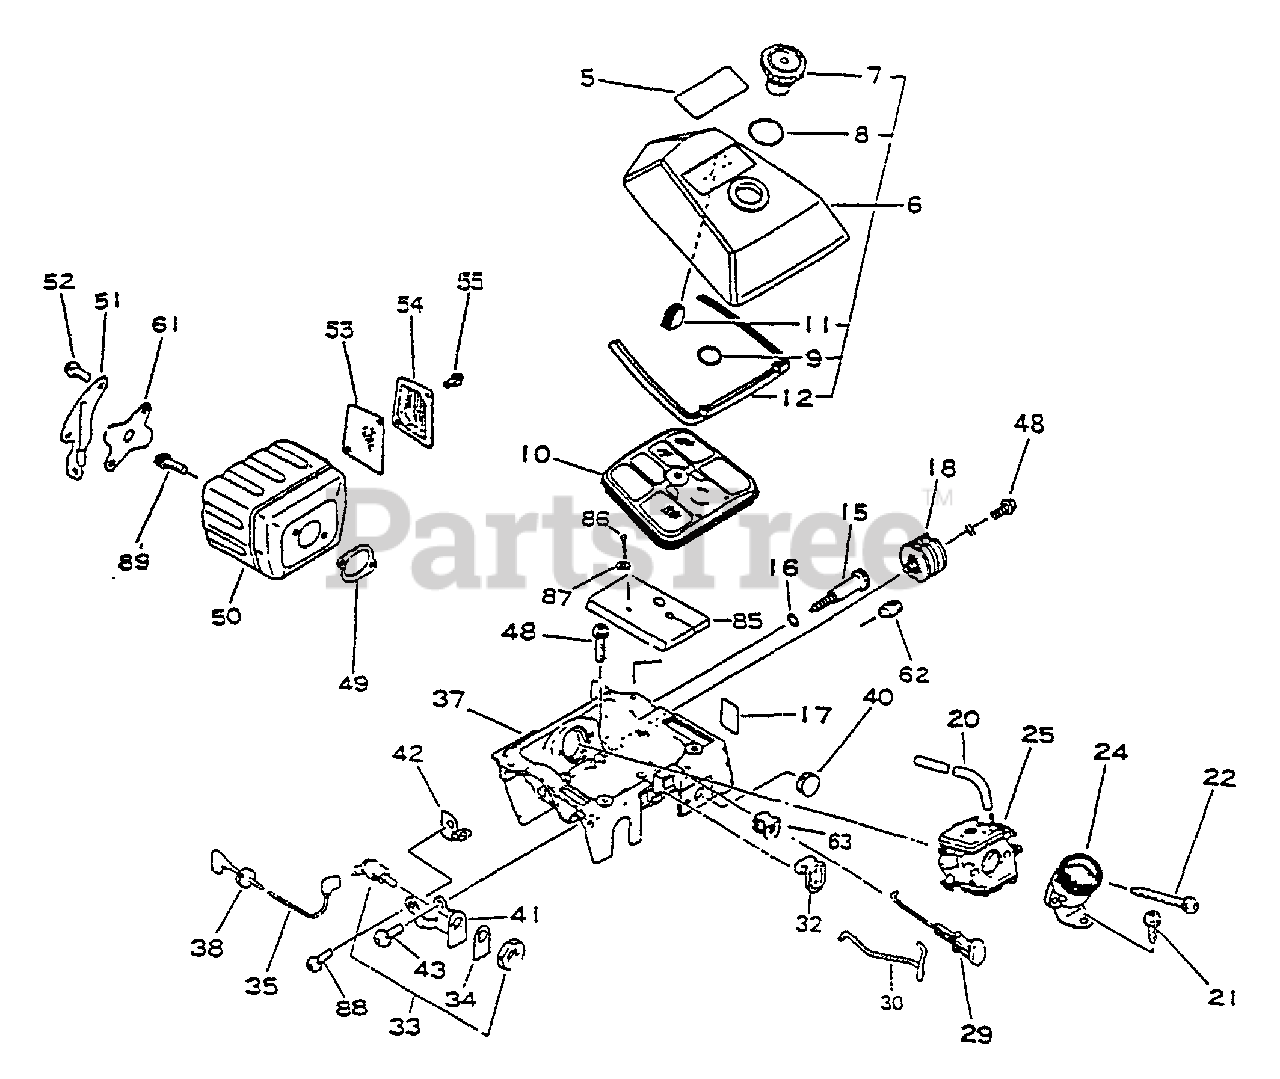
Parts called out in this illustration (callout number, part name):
5	LABEL, CS-5500
6	COVER ASSY, AIR FILTER
7	THUMBSCREW
8	O-RING 22
9	O-RING P-11
10	FILTER ASSY, AIR
12	GASKET, AIR FILTER
15	SCREW, IDLE ADJUST - GRAY
16	O-RING 7 MM
17	LABEL, CAUTION - IDLE
20	PIPE, IMPULSE
21	SCREW 5×14
22	SCREW - 5×35
24	ADAPTER, INTAKE
25	CARBURETOR
29	ROD, CHOKE
30	ROD, THROTTLE
32	ROD, THROTTLE
33	SWITCH, ON-OFF
34	LABEL - SWITCH
35	LEAD - GROUND
37	CASE, CARBURETOR
41	BRACKET, SWITCH
42	PLATE, GROUND
43	SCREW 5×14
48	SCREW 5×20
49	GASKET, EXHAUST
50	MUFFLER
51	BRACKET, MUFFLER
52	BOLT 5×14
53	SCREEN, SPARK ARRESTER
54	COVER, MUFFLER
55	BOLT 4×10
61	COVER, MUFFLER
63	GROMMET
85	GASKET, CARBURETOR CASE
86	PIN, COTTER 3×18
88	SCREW 4×10
89	BOLT 5×20
